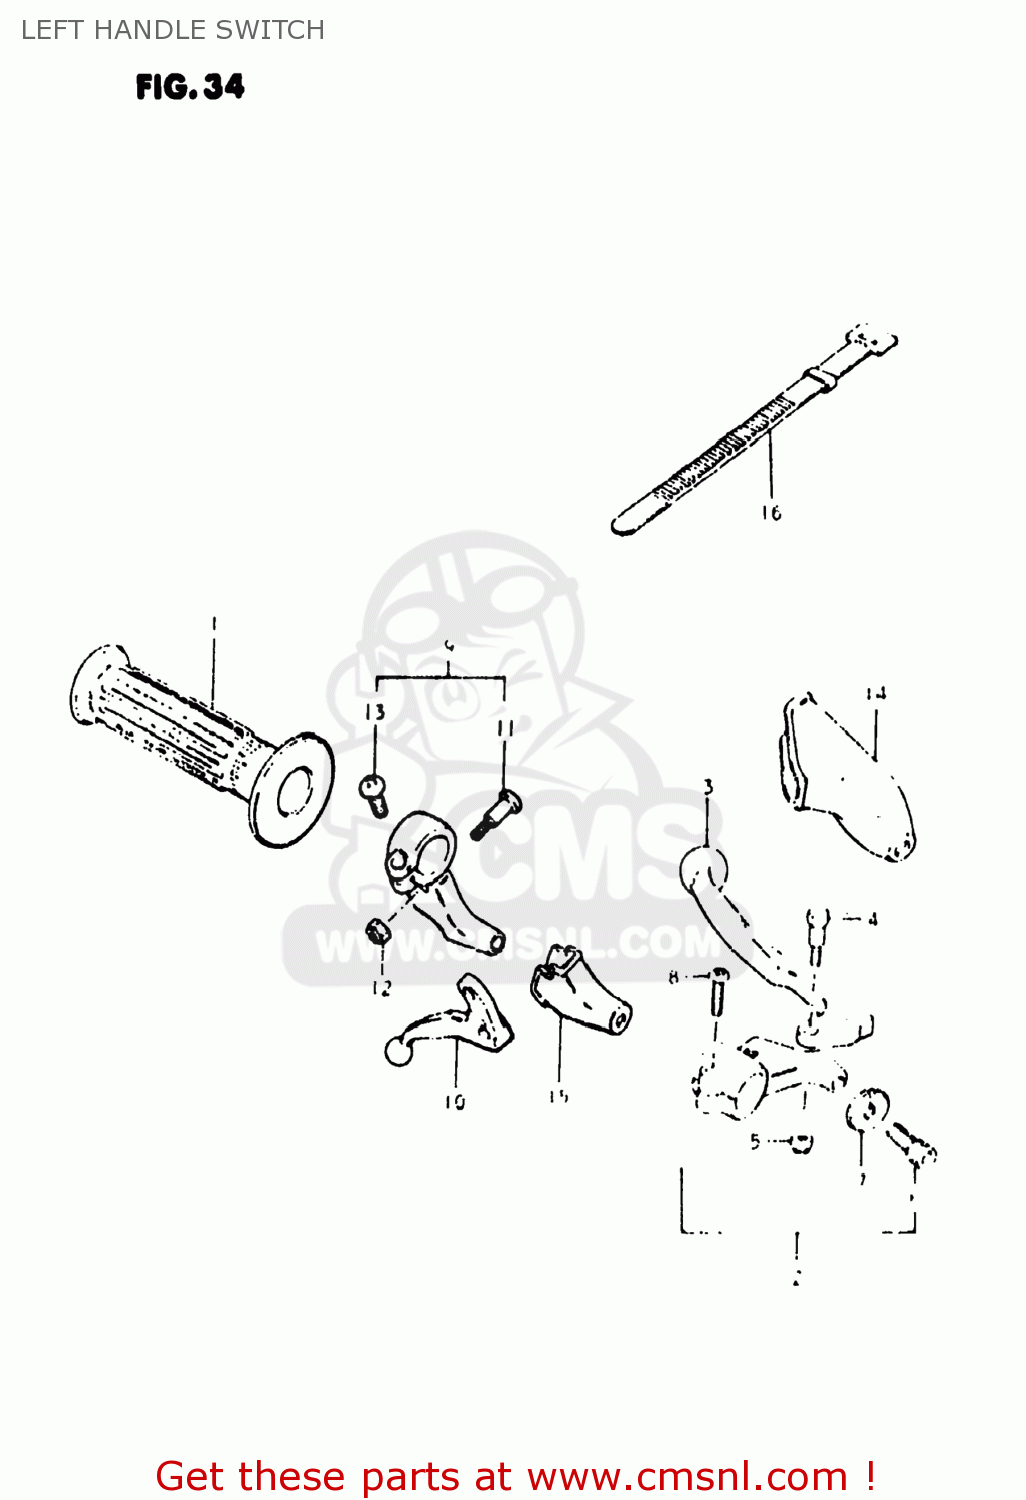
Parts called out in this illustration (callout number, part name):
1	GRIP,L
2	LEVER ASSEMBLY,CLUTCH
3	LEVER,CLUTCH
4	BOLT,LEVER
5	NUT 6MM
6	ADJUSTER,CABLE
7	NUT,CABLE ADJUSTER
8	SCREW
9	LEVER ASSEMBLY,DECOMPRESSION
10	LEVER,DECOMPRESSION
11	BOLT,LEVER
12	NUT,LEVER BOLT
13	SCREW
14	COVER,CLUTCH LEVER
15	COVER,DECOMP LEVER DUST
16	CLAMP(L:120)
